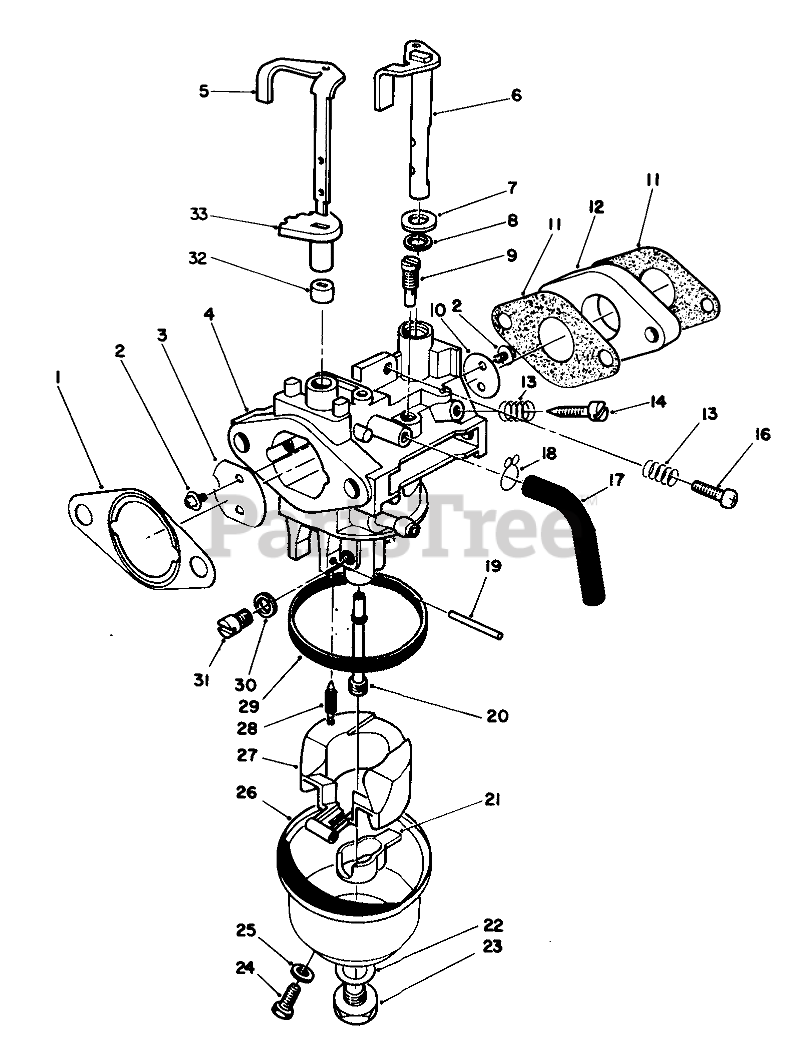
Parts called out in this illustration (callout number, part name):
1	GASKET F/W ENGINE
2	Screw
3	VALVE
4	Body-Carburetor
5	Shaft-Choke Valve
6	SHAFT
7	WASHER
8	Seal-Throttle Shaft
9	JET - PILOT
10	VALVE
11	GASKET INTAKE
12	INSULATOR - CARB.
13	SPRING-PILOT SCREW
14	ADJUSTER
16	SCREW
18	CLAMP
19	Pin
20	NOZZLE - MAIN
21	SPACER
22	GASKET
23	SCREW
24	SCREW
25	GASKET
27	FLOAT
28	NEEDLE
29	FLOAT BOWL GASKET
30	SPACER
31	Plate
32	LOWER CHOKE RING
33	UPPER CHOKE RING
